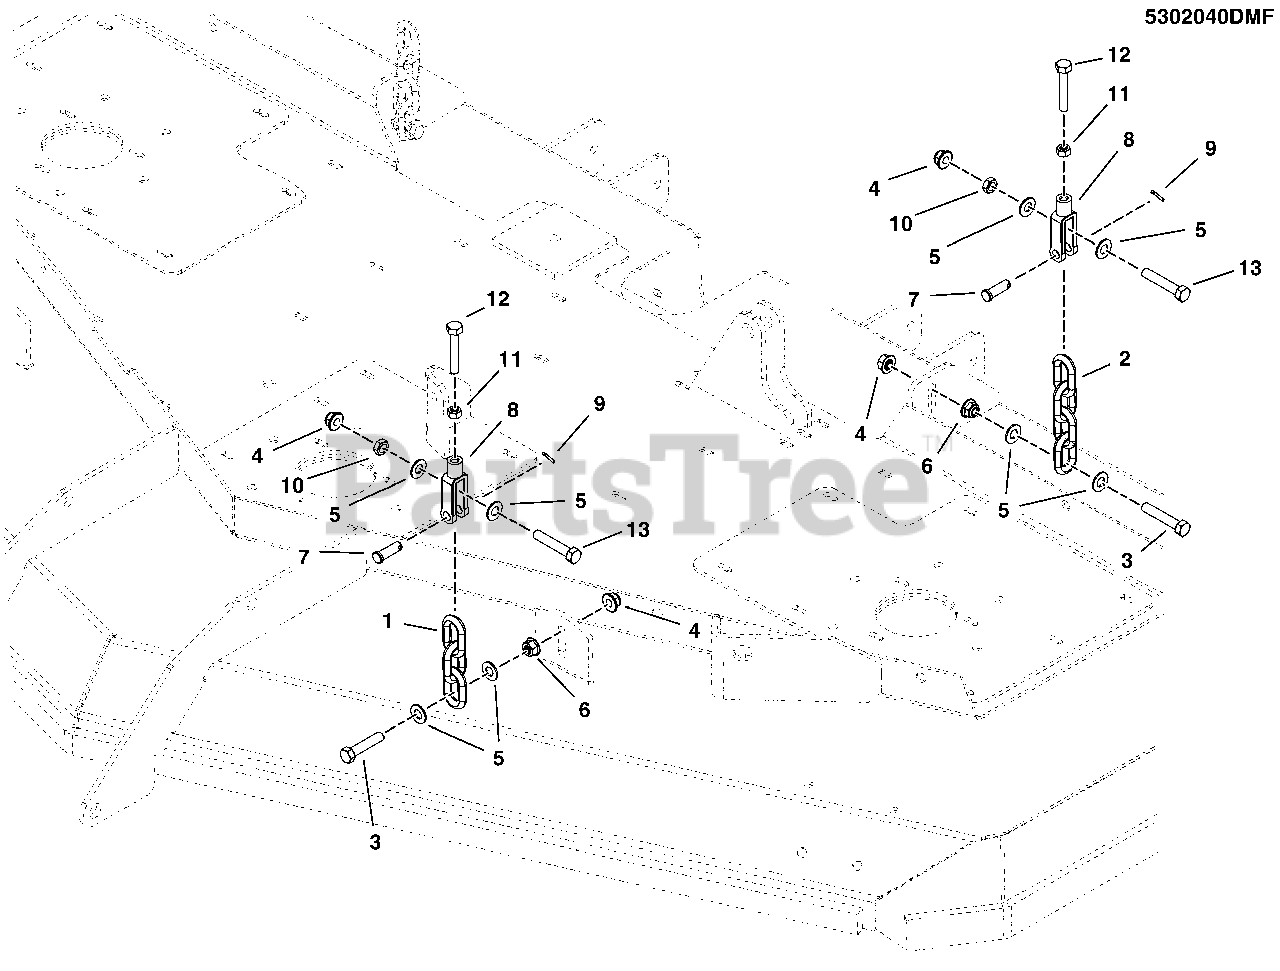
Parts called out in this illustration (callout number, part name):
1	CHAIN, 5/16 GD30, 3 LINKS
2	CHAIN, 5/16" GD30, 4 LINKS
3	BOLT, 3/8-16 X 1-3/4 GD5
4	NUT, 3/8-16 HEX NYLOCK FLANGE
5	WASHER, 3/8 SAE
6	NUT, 3/8-16 HEX SERRATED FLANGE
7	PIN, CLEVIS, 3/8 X 1-1/8, CZ
8	CLEVIS, 5/16-18, 3/8 PIN HOLE, CLR ZINC
9	PIN, COTTER, 3/32 X 3/4
10	NUT, 3/8-16 HEX JAM
11	NUT, 5/16-18 HEX
12	BOLT, 5/16-18 X 2 GD5 TFL
13	BOLT, 3/8-16 X 2 GD5
